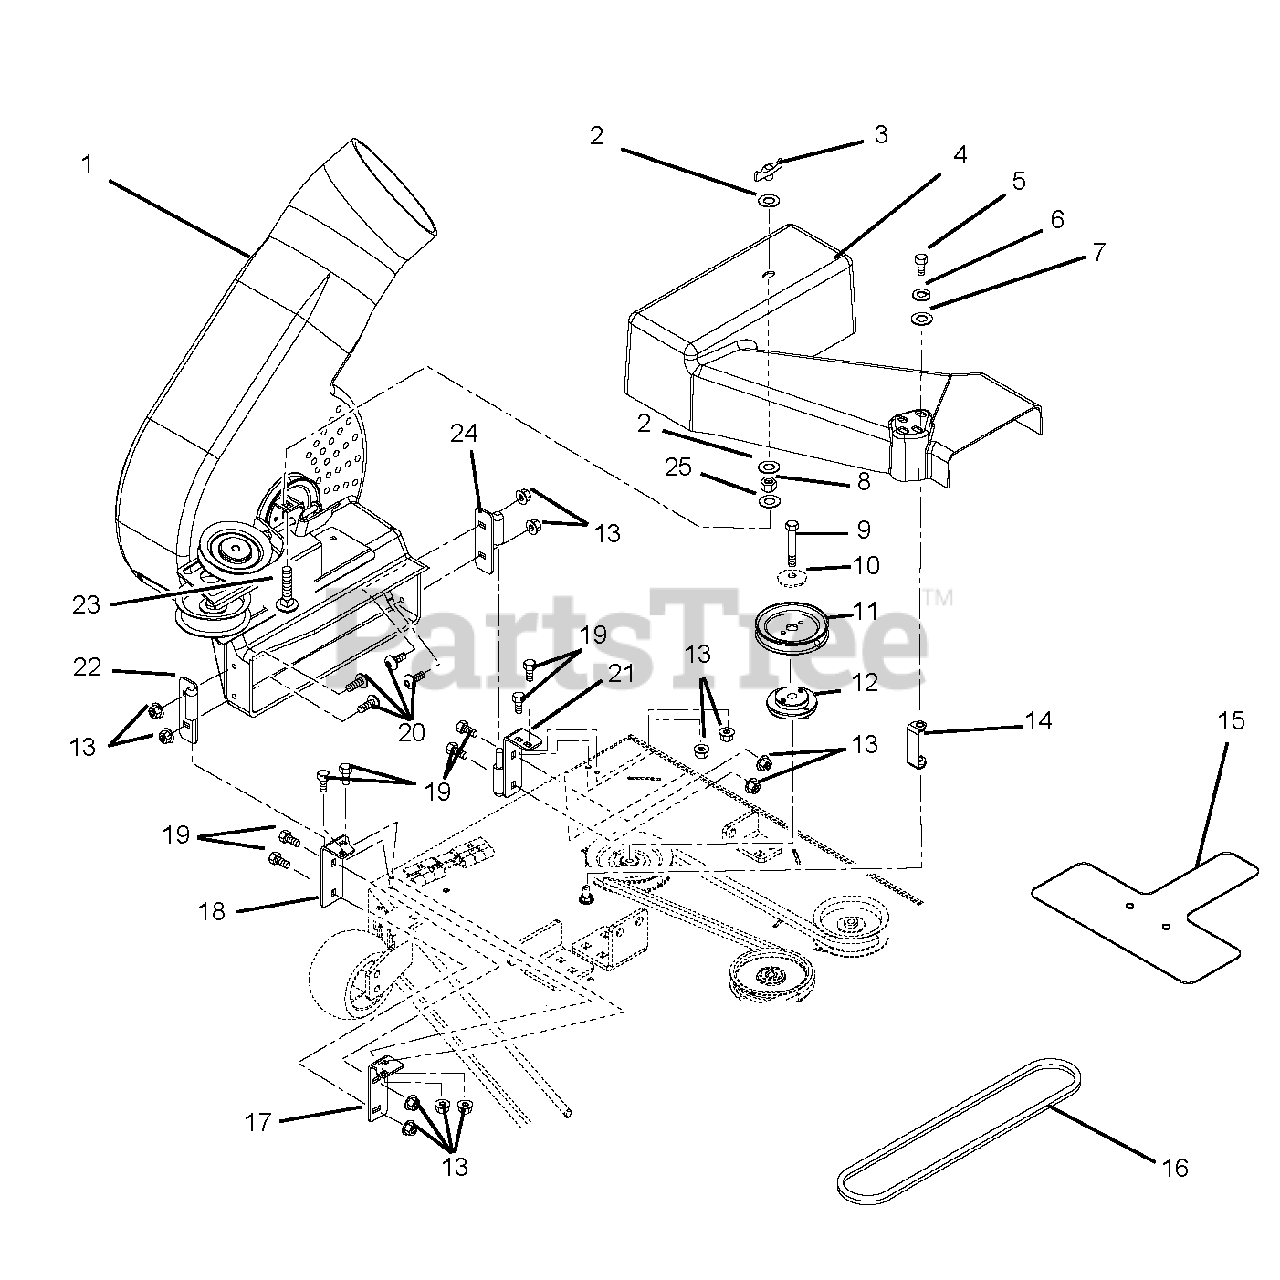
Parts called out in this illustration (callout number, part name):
1	Housing, Blower
2	Washer, Flat-Steel.38 x 1.50 x .062
3	Knob, Wing .312-18
4	Belt Cover
5	Bolt, Hex .38-16 x .75 – Grade 5
6	Washer, Locking .38 x .094 Regular
7	Washer, Flat-Steel .438 x 1.00 x .083
8	Nut, Jam .312-18
9	Bolt, Hex .38-16 x 1.75 – Grade 8
10	Washer, Cupped, .375 (comes with mower deck)
11	Sheave, 3.00 Diameter (40- and 44-inch Mower Decks)
12	Assembly, Sheave Adapter
13	Nut, Locking-Top-Flange .25-20
14	Spacer, Cover
15	Guard, Finger (40-Inch Mower Decks)
16	V-Belt (40- and 44-Inch Mower Decks)
17	Bracket, Front
18	Weldment, Front Mount Bracket
19	Bolt, Hex .25-20 x .75 – Grade 5
20	Screw, Machine .25-20 x .75
21	Weldment, Rear Mount Bracket
22	Weldment, Housing Mount Right Hand
23	Bolt, Round Head Square Neck .31-18 x 1.50
24	Weldment, Housing Mount Left Hand
25	Washer, Flat-Steel .312 x .734 x .065
